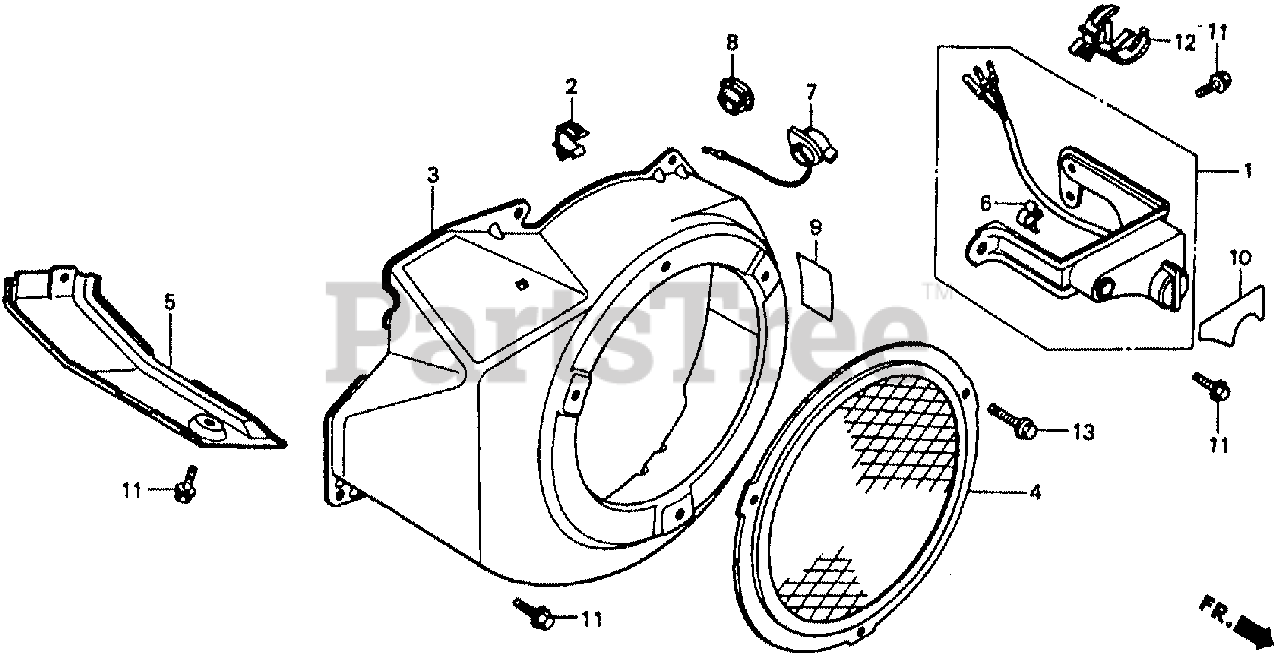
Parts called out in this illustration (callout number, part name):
2	CLIP, TUBE
3	COVER, FAN *R8* (Honda Code 4330981). (BRIGHT RED)
3	COVER, FAN *R280* (Honda Code 7323561). (POWER RED)
4	PROTECTOR, FAN COVER *R8* (Honda Code 4011326). (BRIGHT RED)
5	SHROUD
8	GROMMET, DRAIN HOLE
9	EMBLEM, SUB (EXTERNAL)
10	MARK, OIL ALERT (EXTERNAL)
11	BOLT, FLANGE (6X12) (CT200)
12	CLIP, WIRE HARNESS
13	BOLT, FLANGE (6X8)
